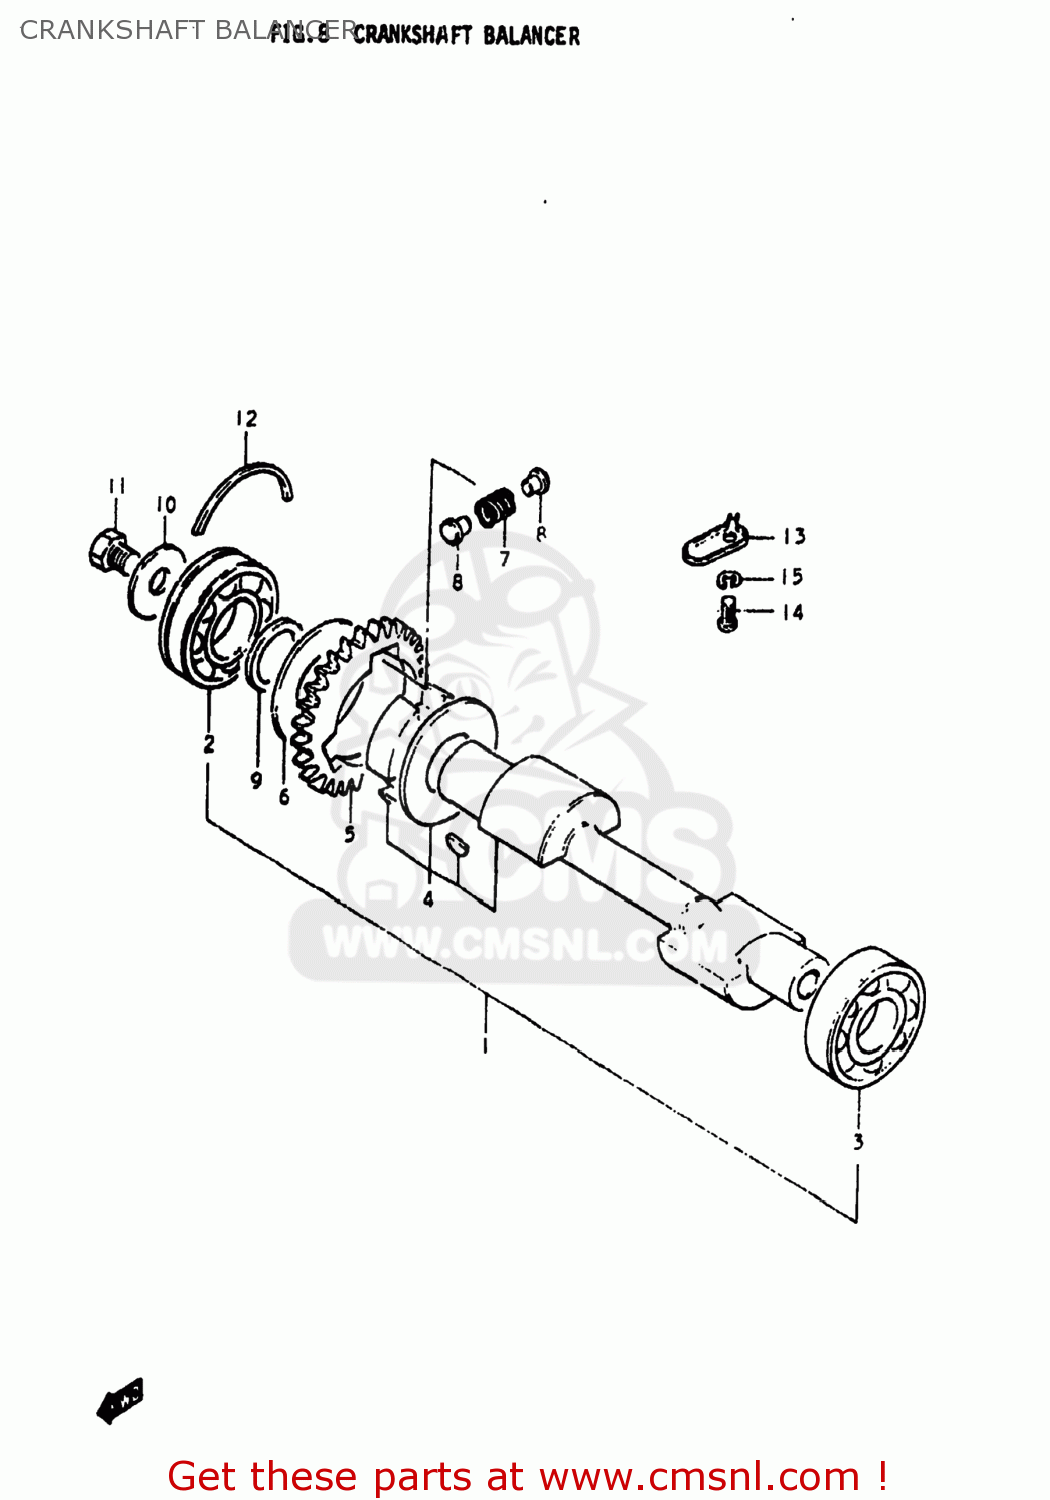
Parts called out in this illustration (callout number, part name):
1	BALANCER,CRANKSHAFT
2	BEARING
3	BEARING
4	CLUTCH SET,STARTER
5	GEAR,CRANK BALANCER DRIVE
6	WASHER (31X70X3)
7	SPRING
8	PIN
9	WASHER
10	WASHER
11	BOLT ,12X16
12	C-RING
13	PLATE, OIL RESERVE
14	SCREW
15	LOCK WASHER
